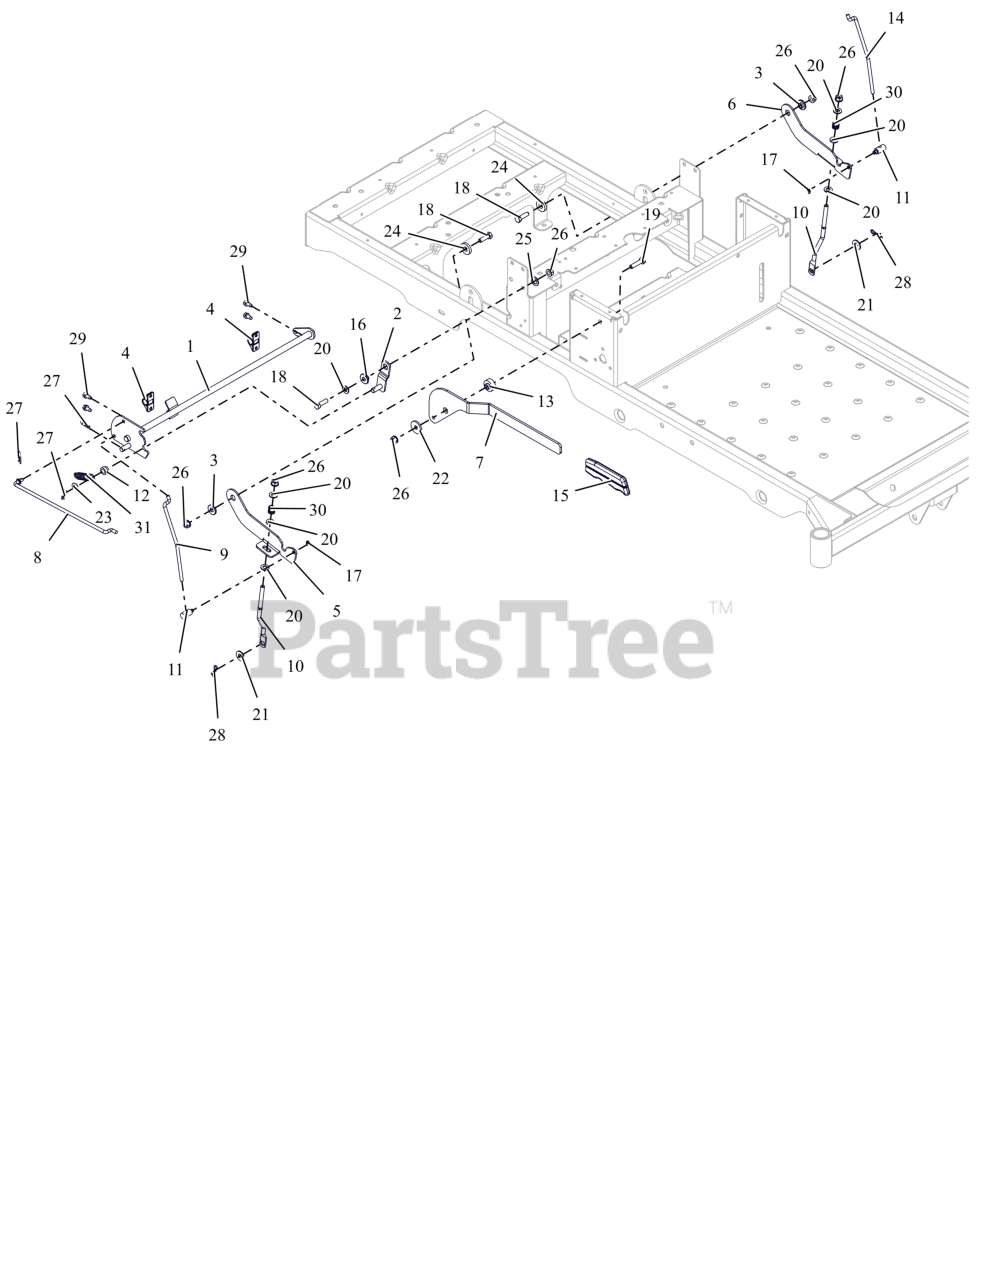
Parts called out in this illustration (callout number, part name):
1	WELDMENT, BRAKE SHAFT
2	WELDMENT,DETENT ARM
3	BSHG, FLG .325X.499X.26X.88
4	BUSHING-.50 CLAMP BLOCK MOLDED
5	LATCH,RH NETURAL
6	LATCH,LH NETURAL
7	HANDLE, PARKING BRAKE
8	LINK, BRAKE HANDLE
9	LINK, NEUTRAL RH
10	LINK, BRAKE COG
11	TRUNION, 1/4-20
13	SPCR,BRAKE .32X.49X.192X1.00
14	LINK, NEUTRAL LH
15	GRIP, PARKING BRAKE (YELLOW)
16	BSHG-FLG .32X.500X.344X.880
17	RG-RTNG-EXT .250X.025
18	BLT,HEX .31-18X1.00 G5 ZCC
19	BLT, HEX .31-18X1.25 G5 ZCC
20	WSHR,FLT .344X.688X.065 ZCC
21	WSHR,FLT .375X.875X.083 ZCC
22	WSHR, FLT .340X1.125X.135 ZCC
23	WSHR, FLT .385X.745X.030 ZCC
24	WSHR, FLT .406X1.00X.188 ZCC
25	WSHR, FLT .520X.827X.062 ZCC
26	NUT,LK-CTR-FLG .31-18 GF ZCC
27	PIN, HAIR #213 .08X1.19 ZCC
28	PIN, BOWTIE #72 ZCC
29	SCR-TAP .25-20X.50 HWH ZCC
30	SPRING, COMPRESSION
31	SG-TENS .072X.565X1.87
